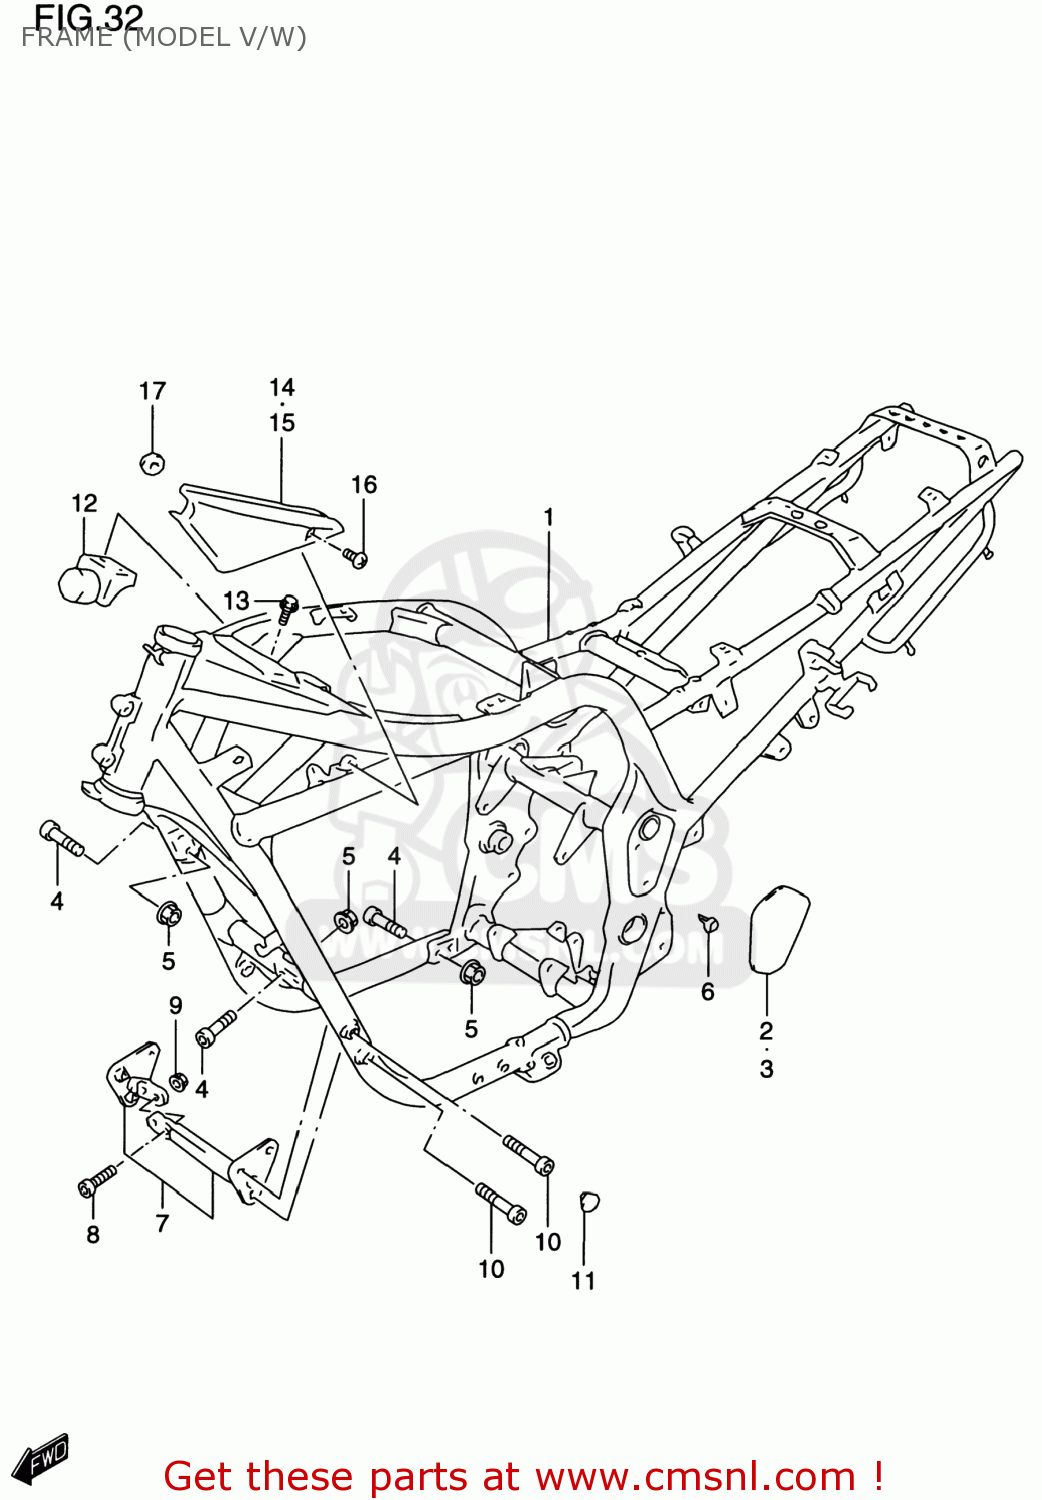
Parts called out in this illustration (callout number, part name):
1	FRAME COMP
2	COVER,FRAME BODY,R
3	COVER,FRAME BODY,L
4	BOLT(10X33)
5	NUT
6	CLIP
7	PLATE ASSEMBLY,ENGINE MOUNT
8	BOLT
9	NUT
10	BOLT
11	CAP(OD:12)
12	DAMPER COMP,FRAME
13	BOLT
14	COVER,FRAME HEAD,R
15	COVER,FRAME HEAD,L
16	SCREW(5X12)
17	CUSHION
